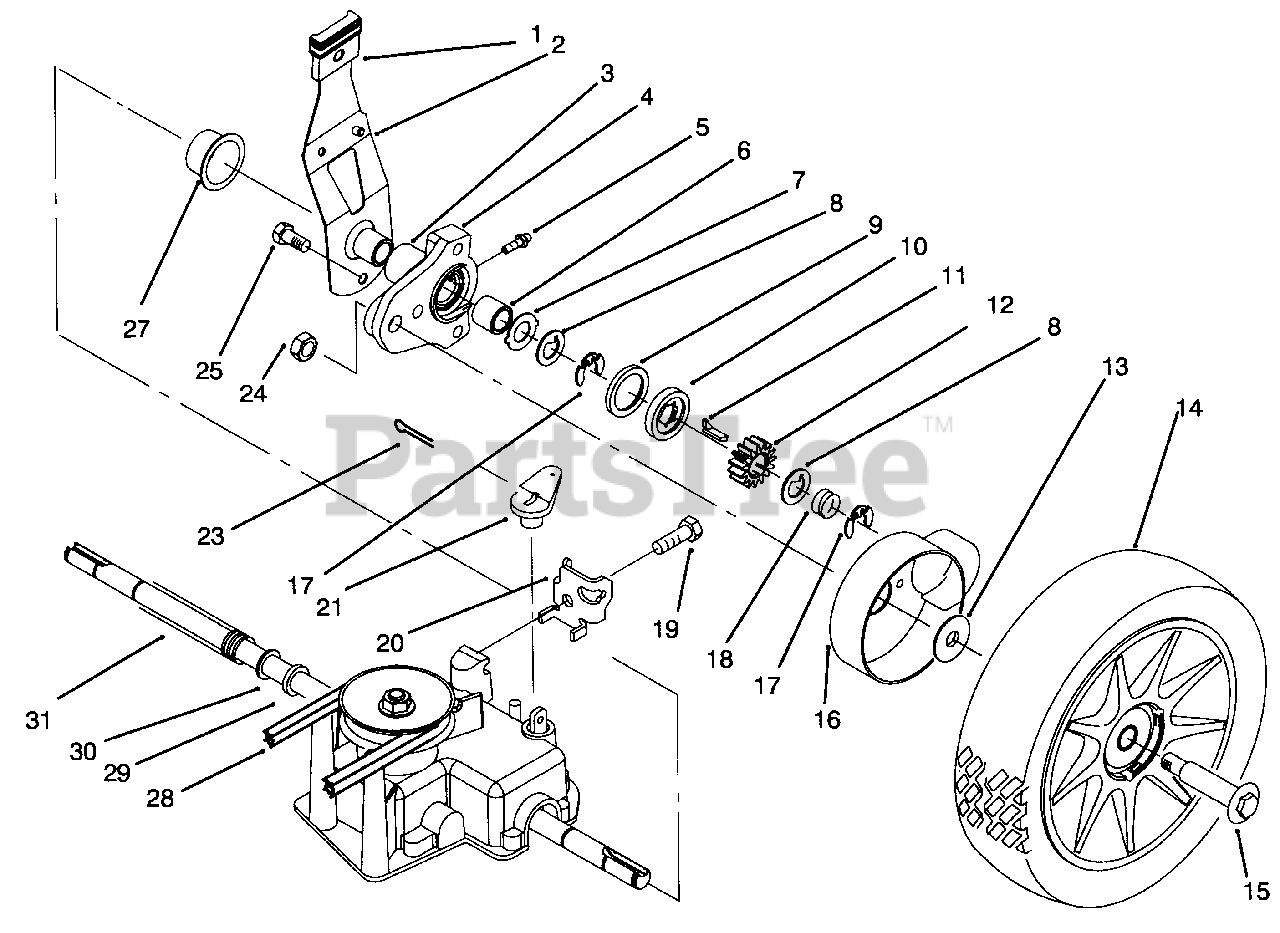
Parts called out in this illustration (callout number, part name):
1	Knob-Spring Arm (Ref.)
2	Spring Arm Assembly L.H.
4	Pivot Arm Assembly
5	Fitting-Grease (Ref.)
7	Washer-Thrust
8	Washer-Thrust
9	Ring-Friction
10	Washer-Clutch
11	Key-Rocking, L.H.
12	Gear-Pinion
13	Washer-Stepped
14	Wheel-8"
15	Bolt-Wheel
16	Cover-Wheel
17	Ring-Retaining
18	Spring-Compression
19	Screw-Hex. Hd.
20	Retainer-Cable
21	Lever-Shift
23	Pin-Cotter
29	Washer-Felt
30	Washer-Flat
31	Cover-Drive Shaft
